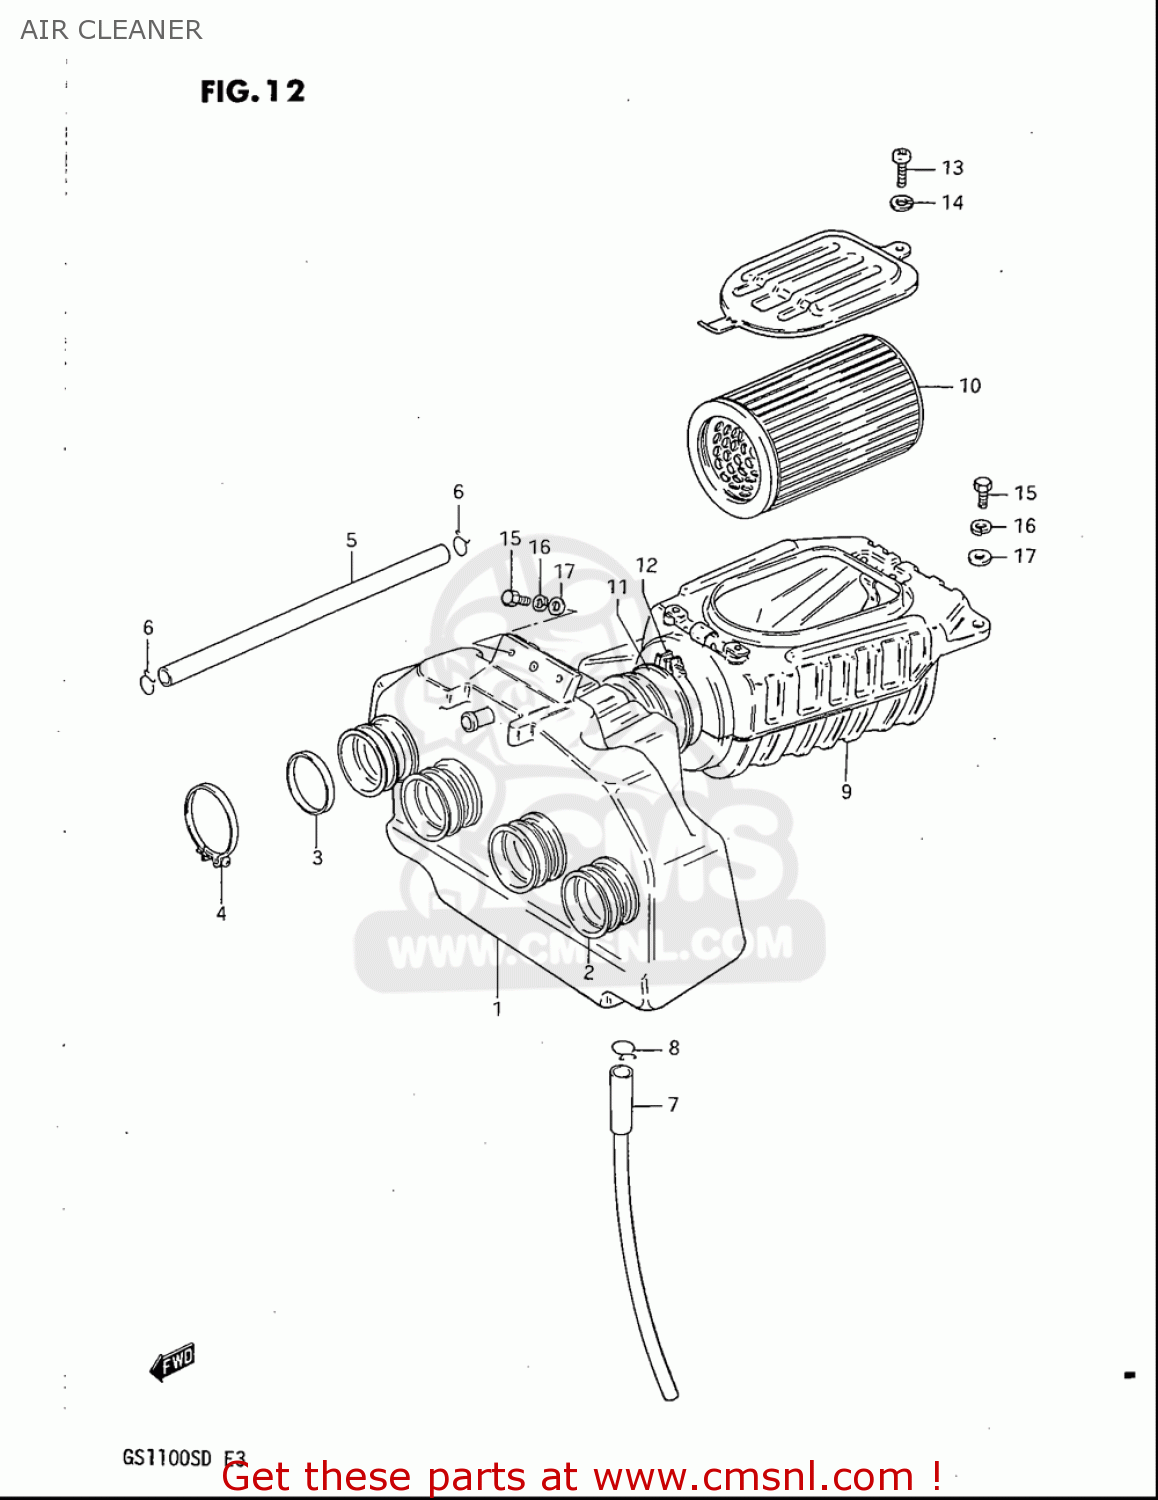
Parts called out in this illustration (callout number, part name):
1	CASE,AIR CHAMBER
2	TUBE,AIR CLEANER OUTLET
3	RING,CARBURETOR AIR INLET HOSE
4	CLAMP
5	HOSE(11X15X2000)
6	CLIP
7	TUBE,DRAIN
8	CLIP
9	CLEANER SET,RR AIR
10	FILTER ASSY
11	HOSE,AIR CLEANER
12	BAND
13	SCREW
14	WASHER,LOCK
15	BOLT
16	WASHER,LOCK
17	WASHER
